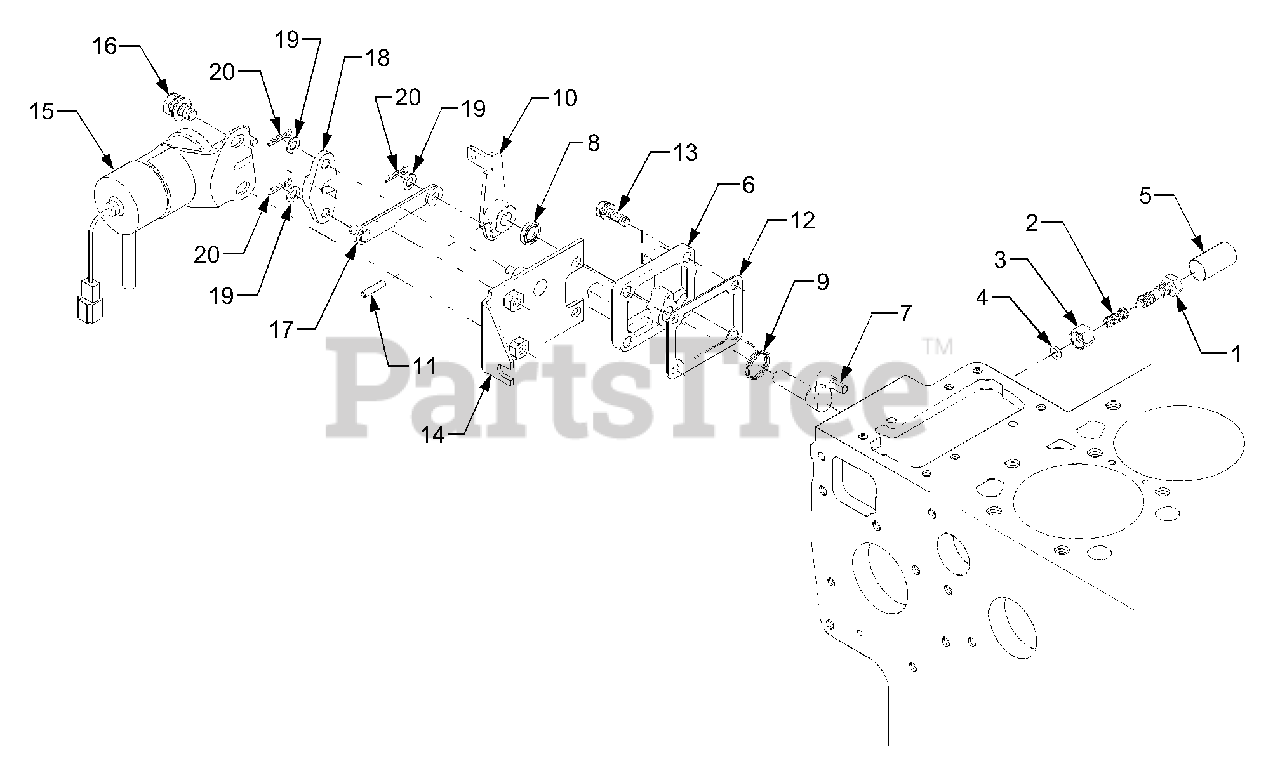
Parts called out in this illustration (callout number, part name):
1	Bolt, Adjusting
6	Cover, Injection Pump
10	Lever, Engine Stop
14	Support, Solenoid
15	Solenoid, Engine Stop
17	Lever 1, Stop
18	Lever 2, Stop
19	Washer, Plain
